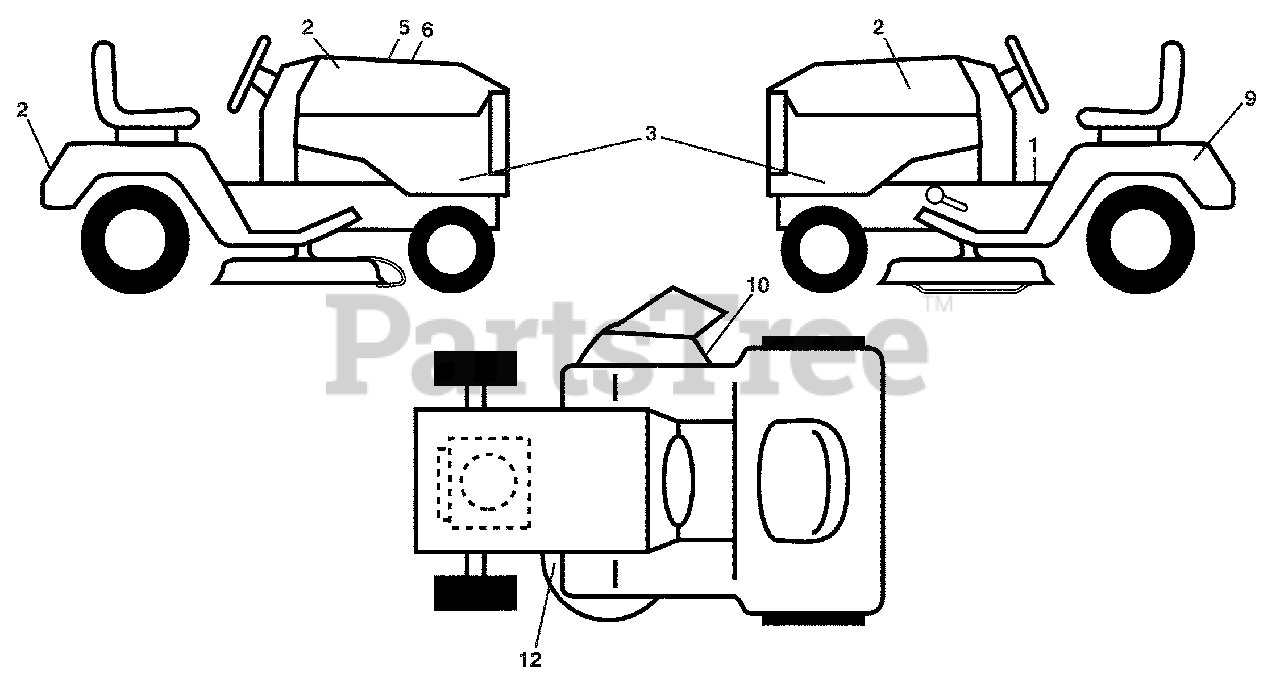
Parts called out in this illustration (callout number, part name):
1	Decal, Warning
2	Decal, Hood
3	Decal, Hood Panel SD
5	Decal, Customer Respons.
6	Decal, Replacement
9	Decal, Battery Dnge/Poi
10	Decal, Warning
12	Decal, Mower V-Belt Schematic
